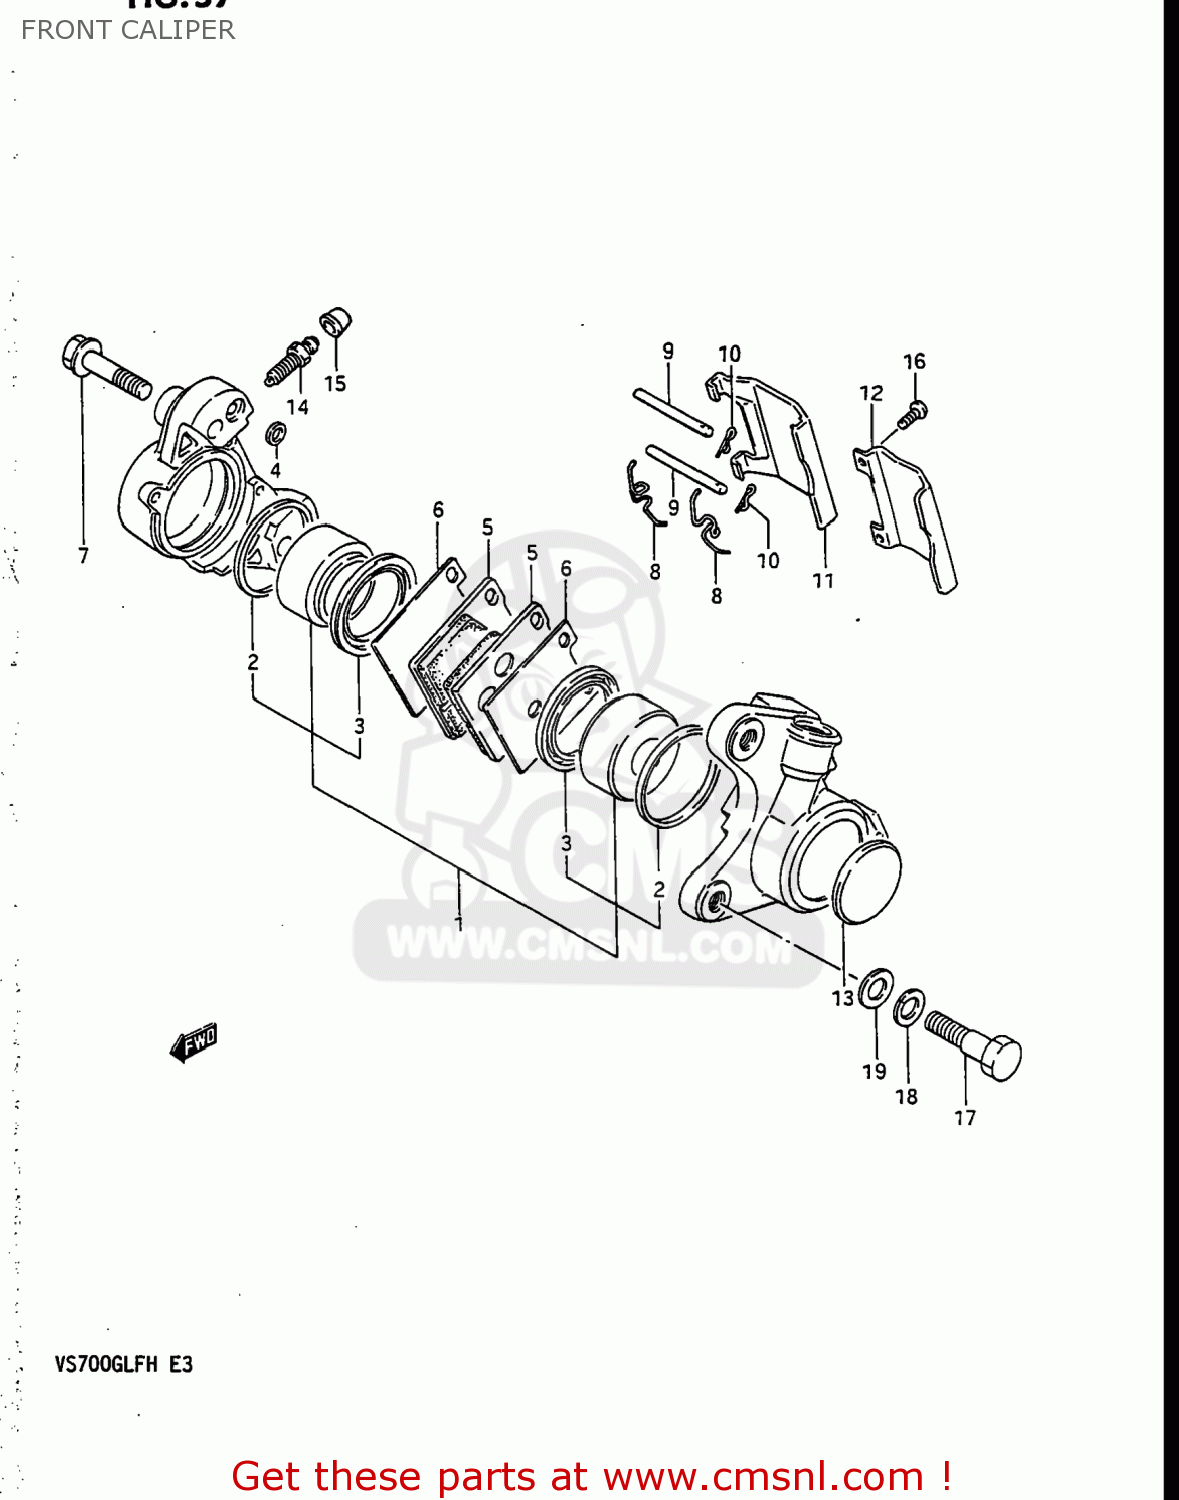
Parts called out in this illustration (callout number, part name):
1	PISTON SET
2	SEAL,FR CALIPE
3	BOOT,PISTON
4	SEAL,JOINT
5	PAD
6	SHIM,PAD
7	BOLT,HOUSING
8	SPRING
9	PIN,PAD
10	CLIP,PAD PIN
11	COVER
12	COVER,CALIPER
13	CAP,CALIPER
14	BLEEDER
15	CAP,BREATHER
16	SCREW,CALIPER COVER (4X
17	BOLT(10X38)
18	WASHER,LOCK,10
19	WASHER
